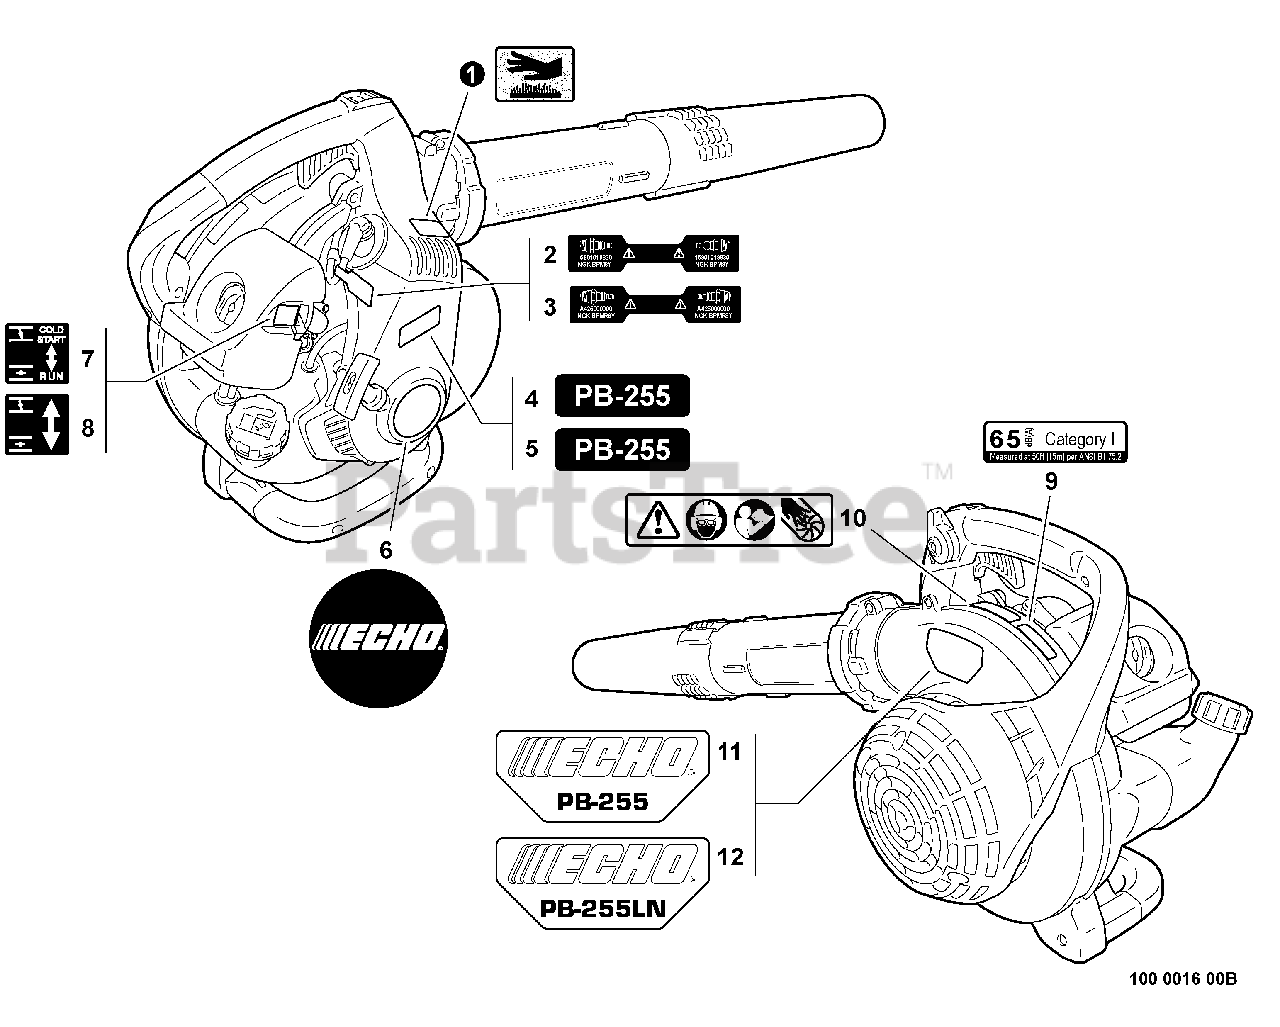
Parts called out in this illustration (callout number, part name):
1	LABEL - HOT SURFACE
2	LABEL - SPARK PLUG -- BPM-8Y
3	LABEL - SPARK PLUG -- BPMR-8Y
4	LABEL - MODEL PB-255
5	LABEL - MODEL PB-255LN
6	LABEL - ECHO
7	LABEL - CHOKE
8	LABEL - CHOKE
9	LABEL - NOISE 65dB(A) CAT I
10	LABEL - CAUTION
11	LABEL - MODEL PB-255
12	LABEL - MODEL PB-255LN
